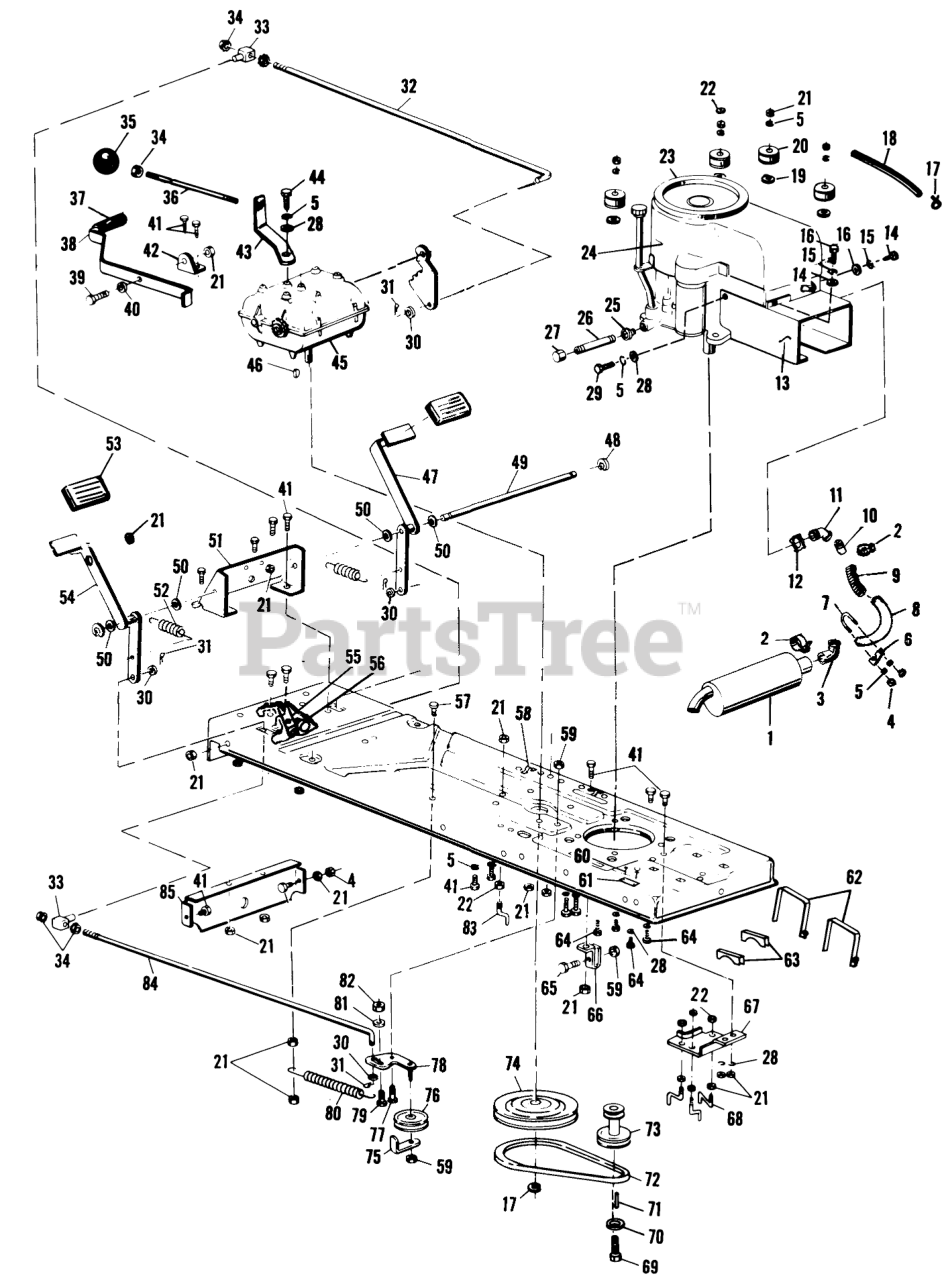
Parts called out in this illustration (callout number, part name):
1	Muffler
2	Clamp, Muffler
3	Elbow, Muffler
4	Nut
5	Lockwasher, 5/16 In.
6	Saddle, Muffler Clamp
7	U-Bolt, Muffler Clamp
8	Pipe, U-Bend, Exhaust
9	Exhaust Tube, Flexible
10	Nipple, 3/4 In.
11	Street Elbow, 45 Degrees
12	Lock Ring, Exhaust
13	Housing-Blower (Inner)
14	Bolt-1/4-20 x 5/8
15	Lockwasher
16	Washer
17	Snap Ring
18	Tube, Drain
19	Spring Washer
20	Spacer, Engine
21	Nut-Nylok
22	Nut 5/16-18 Keps
23	Gasket, Air Intake
24	Engine
25	Reducer
26	Extension, Oil Drain
27	Plug, Pipe
28	LOCKWASHER
29	Screw, Hex Hd, 5/16-18 x 5/8 In.
30	Washer
31	Cotter Key
32	Rod, Brake
33	Pivot Block
34	Nut, Jam, 3/8-24 Thd
36	Rod, Shift Handle
37	Hand Grip
38	Parking Brake Arm
39	Shoulder Bolt
40	Spring Washer
41	Bolt 5/16-18 x
42	Bracket, Parking Brake
43	Shift Handle
44	Screw, Hex Hd, 5/16-24 x 3/4 In.
45	Transmission, 4 speed (See Seperate List pages 4 & 5)
46	Key
47	Pedal Assembly, R.H.
48	"E" Ring
49	Pedal Shaft
50	Washer
51	Bracket, Pedal Support
52	Spring
53	Pedal Pad
54	Pedal Assembly, L.H.
55	Bracket, Pedal Switch
56	Safety Switch
57	Bolt 5/16-18 x 11/4
58	Press Clip
59	Nut
60	Drive Screw, No. 6 x 5/16 In.
61	Plate, Model Number
62	Strap, Muffler
63	Bracket, Muffler Spacer
64	Bolt-Hex 3/8-16 x 2
65	Shoulder Bolt
66	Bracket, Mower Deck Guide
67	Spacer, Pivot Bolt
68	Belt Guide, Engine
69	Screw, Hex Hd, 7/16-20 x 1 In.
70	Lockwasher 3/8
71	Key, Square, 1/4 x 1/4 x 2 1/2 In.
72	V-Belt, 4L-38.8
73	Engine Pulley
74	Transmission Pulley
75	Arm, Idler
76	Idler Pulley
77	Shoulder Bolt
78	Belt Idler Assembly
79	Bolt Hex 1/4-20 x 1 3/4
80	Clutch Spring
81	Nut 1/4-20 Keps
82	Nut-Nylok
83	Belt Guide, Transmission
84	Rod, Clutch
85	Plate, Front Axle Support
96	Service Rod (Not Illust.)
